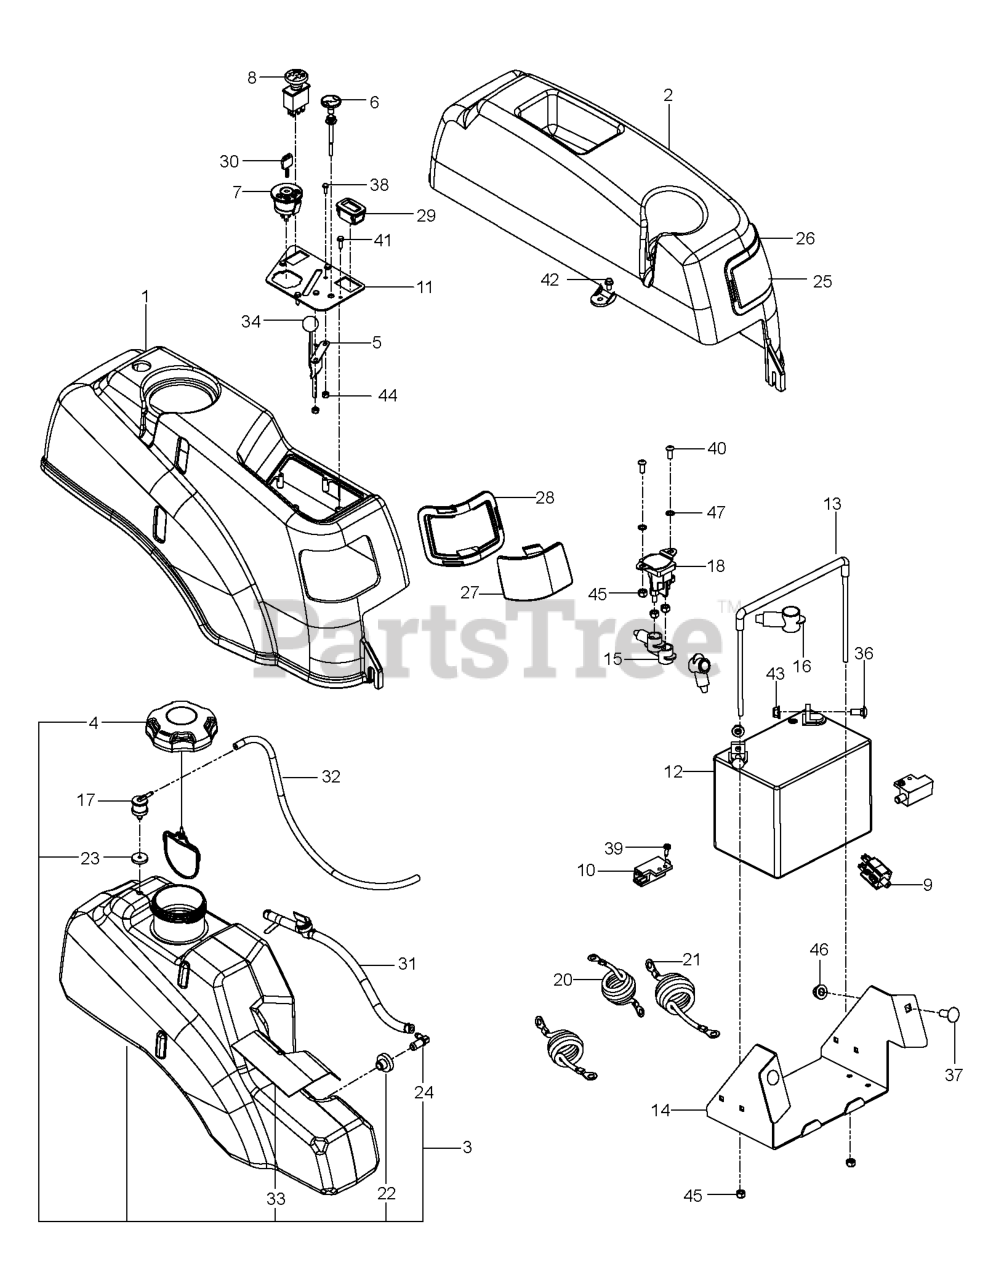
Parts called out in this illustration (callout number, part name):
1	FENDER RT, GRAY
2	FENDER, LT
3	TANK.FUEL.ASSEMBLY.LARGE
4	CAP, FUEL
5	CABLE, THROTTLE
6	CHOKE CABLE
7	RP IGNITION SWITCH
8	RP.SWITCH, BLADE
9	SWITCH, BRAKE 3P
10	SWITCH, INTERLOCK
11	CONSOLE.PLATE.BLACK
12	BATTERY, 12 V 330 AMP
13	BATTERY TIE DOWN ASSEMBLY
14	BOX, BATTERY, BLACK
15	TERMINAL COVER-SM
17	STEM, FUEL TANK
20	BATTERY CABLE, NEGATIVE
21	CABLE POSITIVE, LONG
22	RUBBER GROMMET
23	GROMMET, CHECK VALVE
24	STEM, FUEL TANK
25	LENS, COLORED LEFT
26	LEFT HEADLIGHT RIM GREY
27	LENS, COLORED RIGHT
28	RT HEADLIGHT RIM GREY
29	HOUR METER
30	KEY
31	FUEL.HOSE.SHUT.OFF.ASM.10".3"
32	HOSE, FUEL, 3/16" X 20"
33	SHIELD, HEAT
34	KNOB.ROUND.BALL.BLACK
36	RP BOLT 5/16-18 X3/4 ZN/YEL GR
37	BOLT D
38	SCREW
39	SCREW #10 X 1/2 SELF TAPPING
40	SCR 1/4-20 X 5/8 BTN SKT HD ZD
41	SCR #10-12X3/4 HEX WAS HD ZD
42	SCREW
43	5/16-18 NYLOC FLANGE NUT
44	NUT 10-24 NYLOC
45	LOCKNUT.NYLOC.1/4-20
46	NUT 3/8-16 HEX FLG NYLOC ZD
47	Washer, Lock, Internal Tooth 1/4
